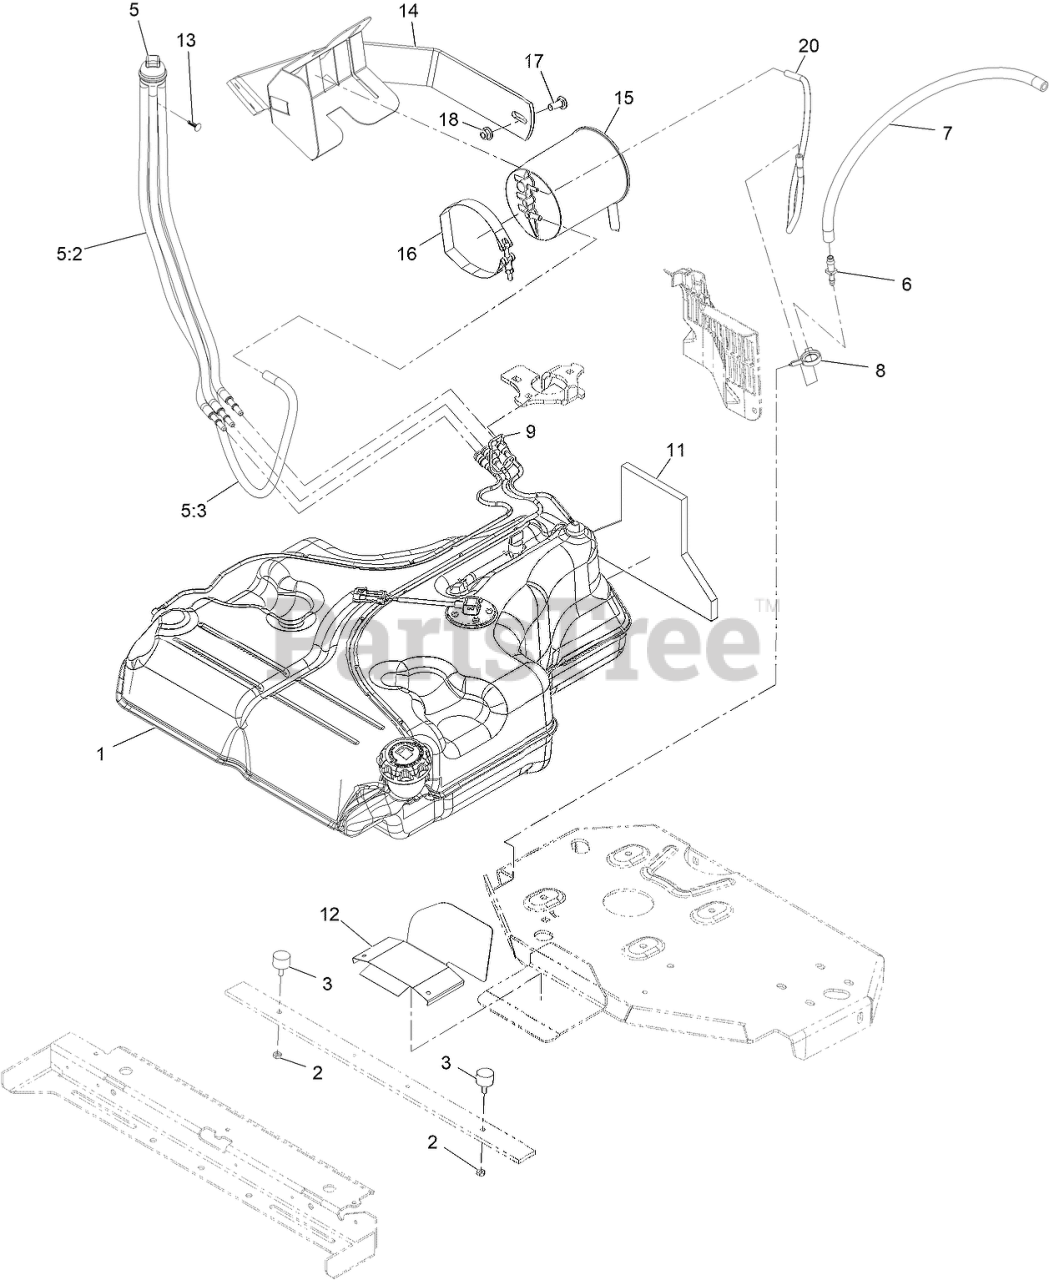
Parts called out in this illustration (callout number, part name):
1	FUEL TANK ASM
2	NUT-JAM
5	FUEL MANIFOLD VENT ASM
5:2	HOSE-FUEL
5:3	HOSE-FUEL
6	FITTING-STRAIGHT
7	HOSE-FUEL
8	CLAMP-HOSE
9	RETAINER-LINE, VAPOR
11	INSULATION-FOAM, FUEL TANK
12	GUARD-EXHAUST
13	PLUG-PLASTIC
14	MOUNT-CANISTER
15	CANISTER-CARBON, 1200CC
16	CLAMP, T-BOLT
17	SCREW-CARR
18	NUT-HF, NI
20	Hose-Vent, Formed
